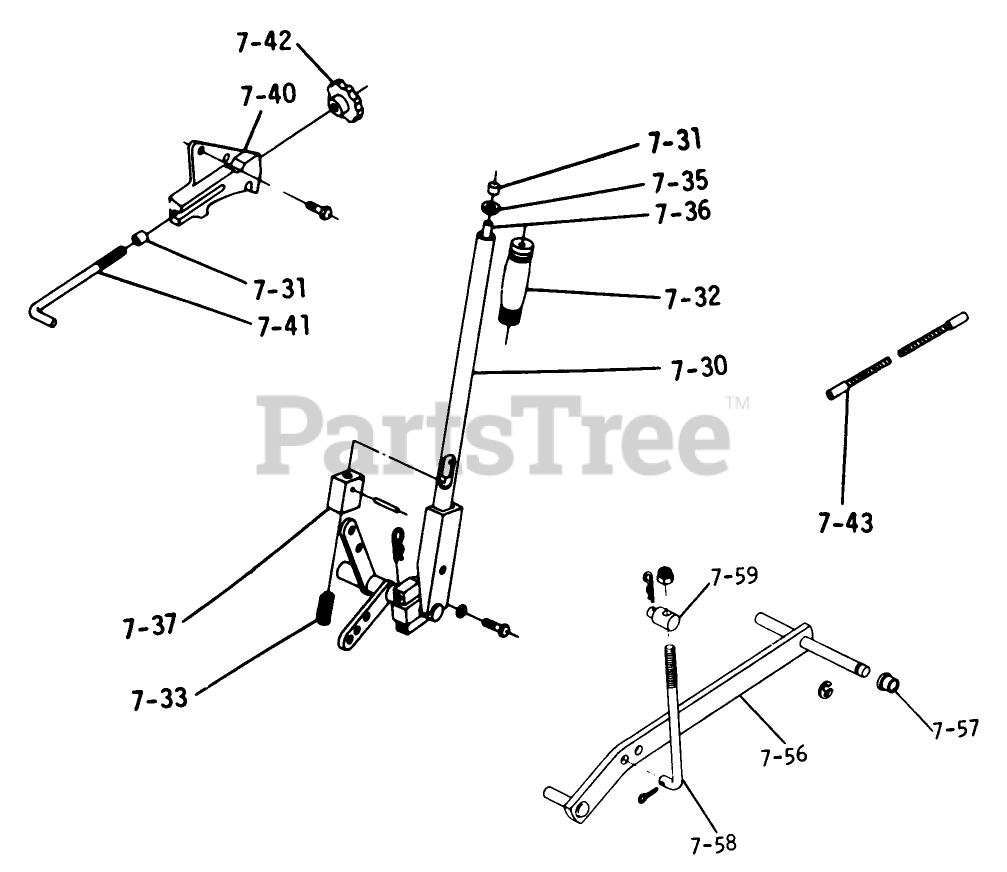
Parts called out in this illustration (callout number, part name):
7-30	Lift Lever
7-31	Cap
7-32	HANDGRIP
7-33	SPRING-COMPRESSION
7-35	Guide-Rod
7-36	PLUNGER ROD
7-37	LOWER PLUNGER R
7-40	Quadrant
7-41	ROD-LIFT CONTROL
7-42	KNOB-LIFT CONTROL
7-43	Conduit
7-56	ASSY LIFT BAR R
7-57	BUSHING
7-58	ROD-LIFT
7-59	TRUNNION-LIFT
